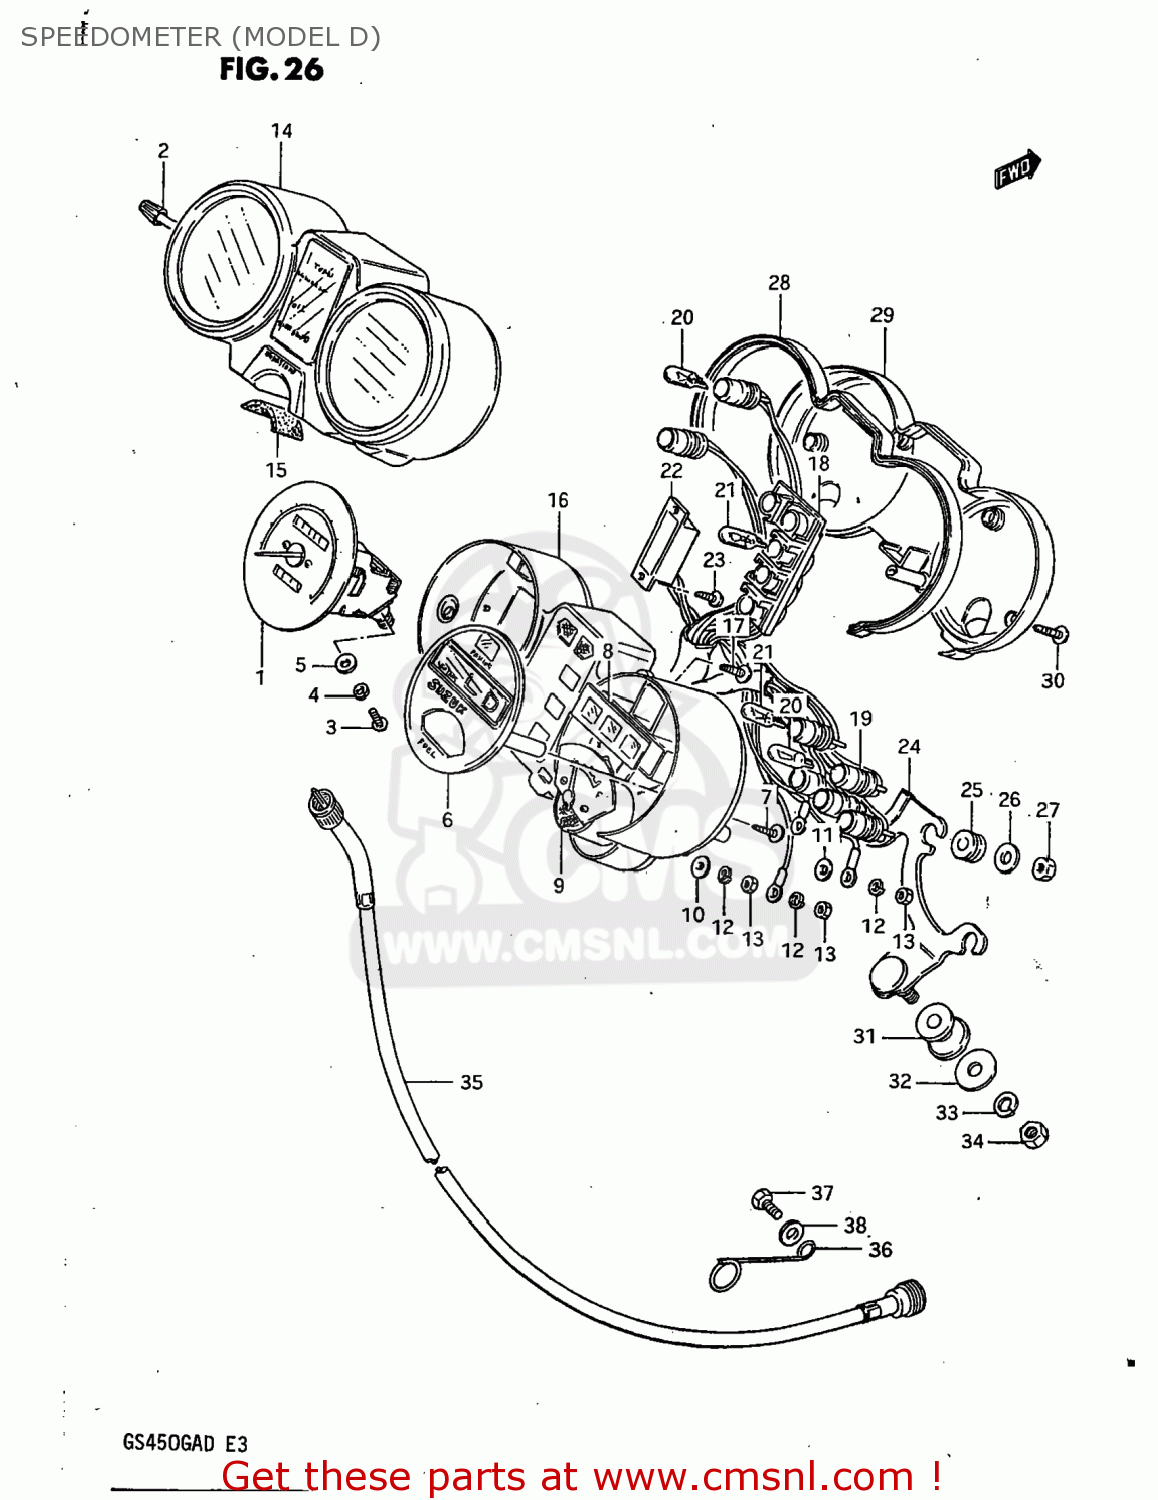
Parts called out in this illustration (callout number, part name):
1	METER,SPEEDOMETER (KM/MPH)
2	KNOB
3	SCREW 4X10
4	LOCK WASHER
5	WASHER
6	PLATE,PILOT PANEL NO.1
7	SCREW,GEAR INDICATOR
8	PLATE,PILOT PANEL NO.2
9	METER,FUEL
10	WASHER
11	WASHER,FUEL METER
12	LOCK WASHER
13	NUT 3MM
14	HOOD,METER
15	SEAL,IGNITION SWITCH
16	CASE,METER,INNER
17	SCREW
18	SOCKET,GEAR INDICATOR
19	SOCKET
20	BULB(12V3.4W,T10)
21	BULB(12V1.7W,T10,WB121)
22	WARNING LAMP,SIDE STAND
23	SCREW,GEAR INDICATOR
24	BRACKET,COMBINATION METER
25	CUSHION,METER
26	WASHER (5.5X16X1.2)
27	NUT
28	COVER,METER,UNDER
29	COVER,LWR
30	SCREW
31	CUSHION,METER BRACKET
32	WASHER (8.5X29X1.6)
33	LOCK WASHER
34	NUT
35	CABLE ASSY,SPEEDOMETER
36	CLAMP,SPEEDOMETER CABLE
37	BOLT, UPPER
38	WASHER
